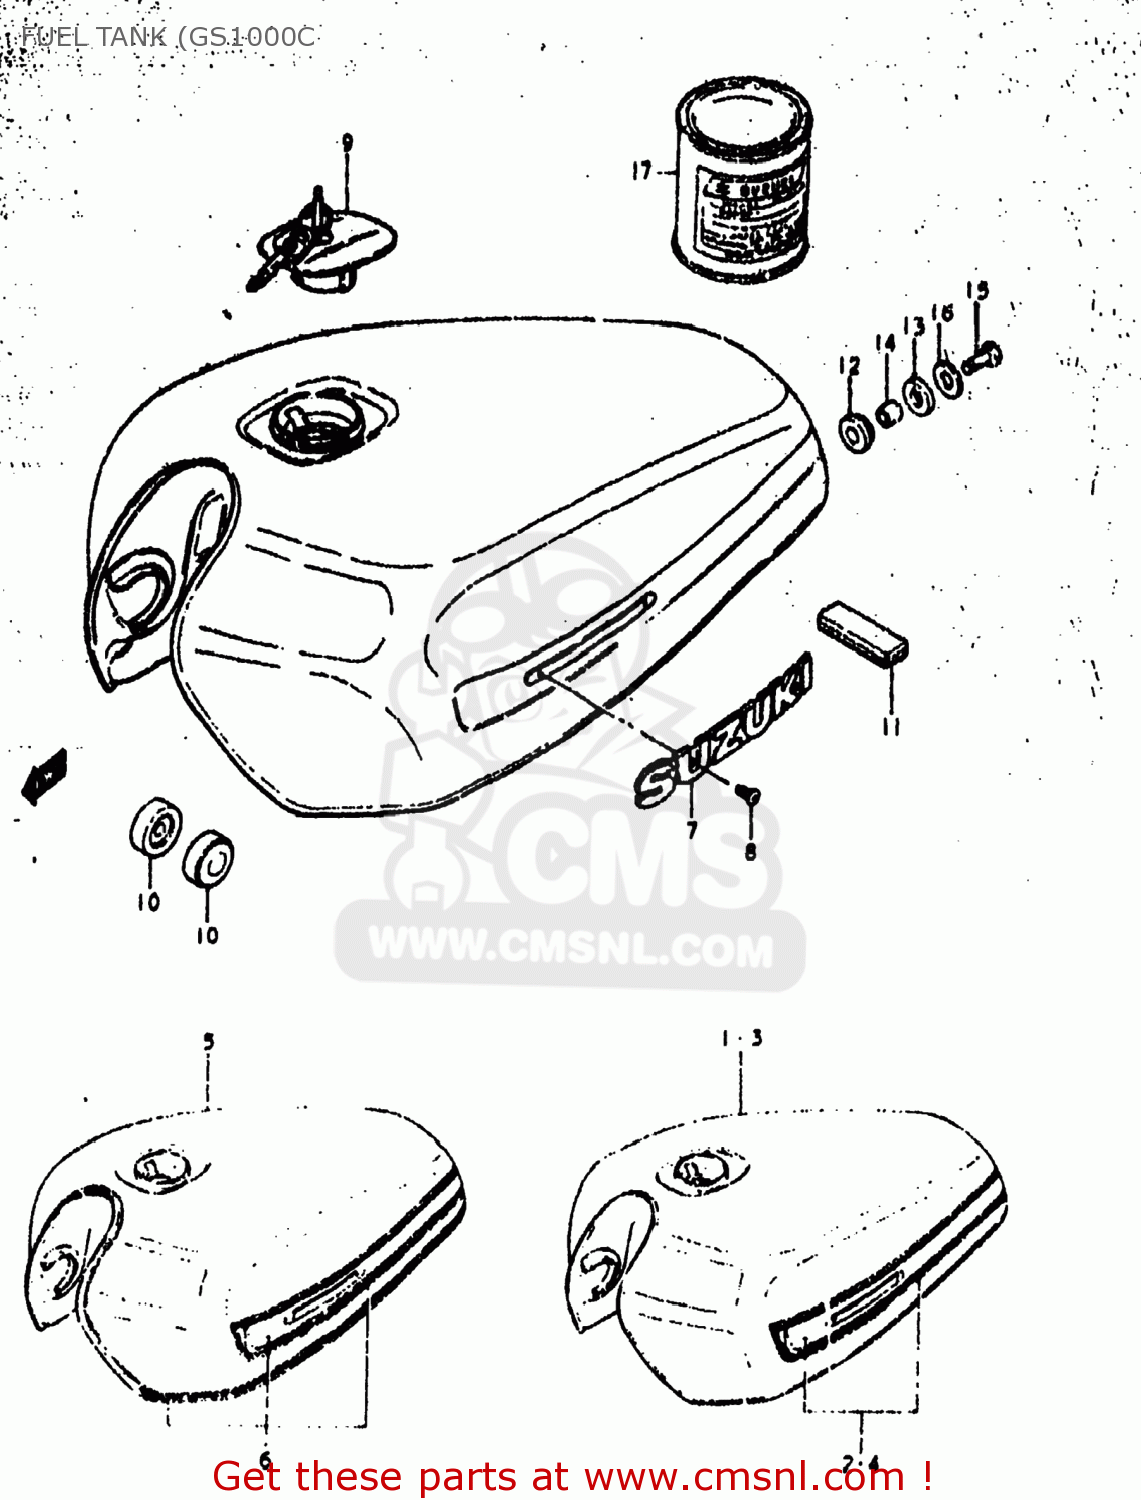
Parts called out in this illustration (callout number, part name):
1	TANK ASSEMBLY,FUEL
3	TANK ASSEMBLY,FUEL
5	TANK ASSEMBLY,FUEL
7	EMBLEM,FUEL TANK
8	SCREW 3X6
9	CAP SET,FUEL TANK
10	CUSHION
11	CUSHION
12	CUSHION
13	CUSHION
14	SPACER(8.5X12X19)
15	BOLT (8X30)
16	WASHER (8.5X29X1.6)
17	PAINT,BLACK
